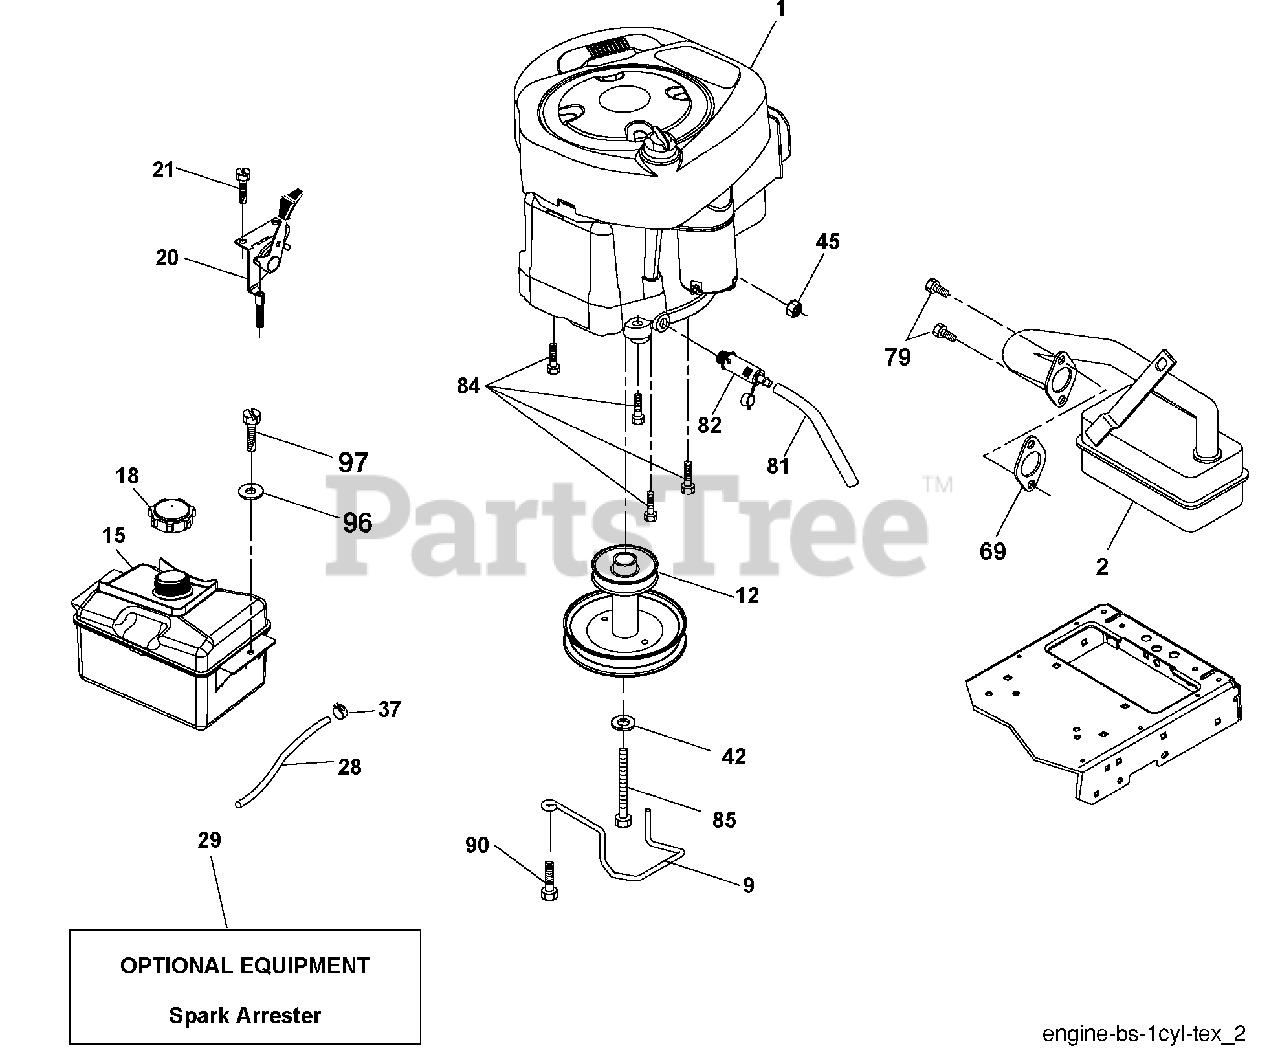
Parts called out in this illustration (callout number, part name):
1	Engine B&S Model No.
2	Muffler
9	Keeper Belt Engine
12	Pulley Engine
15	Tank Fuel
18	Cap Asm
20	Control Throttle
21	Screw #10 x 0.750 BOS
28	Fuel Line
29	Spark Arrester Kit
37	Clamp Hose
42	Washer Lock 7/16
45	Nut Keps Hex 1/4-20 unc
69	Gasket
79	Screw Socket HD 5/16-18 x .75
81	Tube Drain Oil Easy
82	Plug Drain Oil
84	Screw 3/8-16 x 1-1/4
85	Bolt 7/16-20 x 4 x Gr. 5-1.5
90	Screw 3/8-16 x 1
96	Washer 9/32 x 7/8 x 16 Ga.
97	Screw 1/4-20 x 3/4
